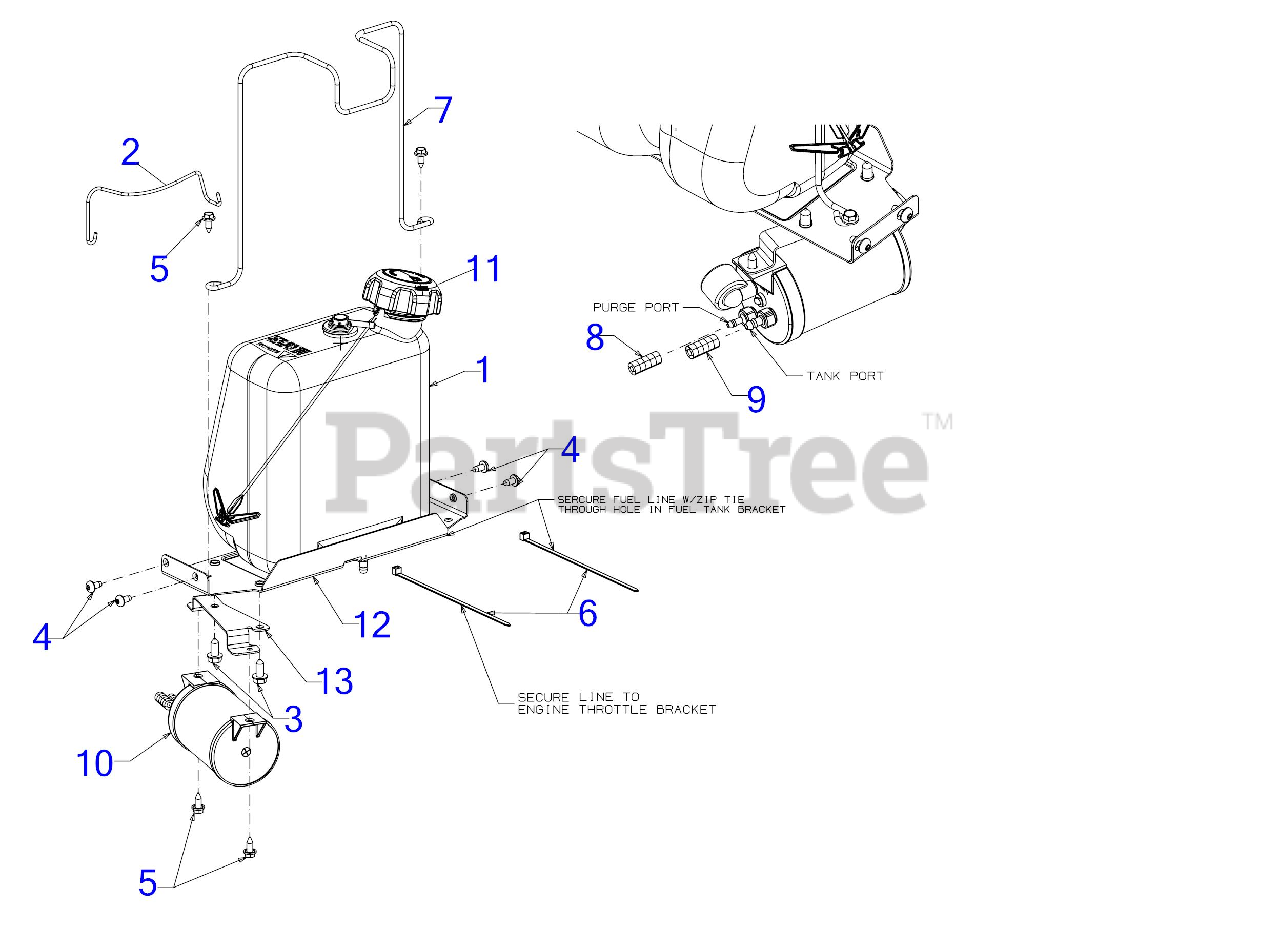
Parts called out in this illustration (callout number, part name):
1	FUEL TANK ASSEMBLY
2	BATTERY ROD ASSEMBLY
3	SCREW 5/16-18 x .750
4	SCREW 1/4-20 x .5
5	SCREW 1/4-20X.625
6	7" CABLE TIE
7	FUEL TANK SUPPORT ROD -
8	FUEL HOSE LO PERMEATION 3/16 WHITE
9	FUEL HOSE LO PERMEATION 7/32 YELLOW
10	CARBON CANISTER
11	FUEL CAP W/TETHER
